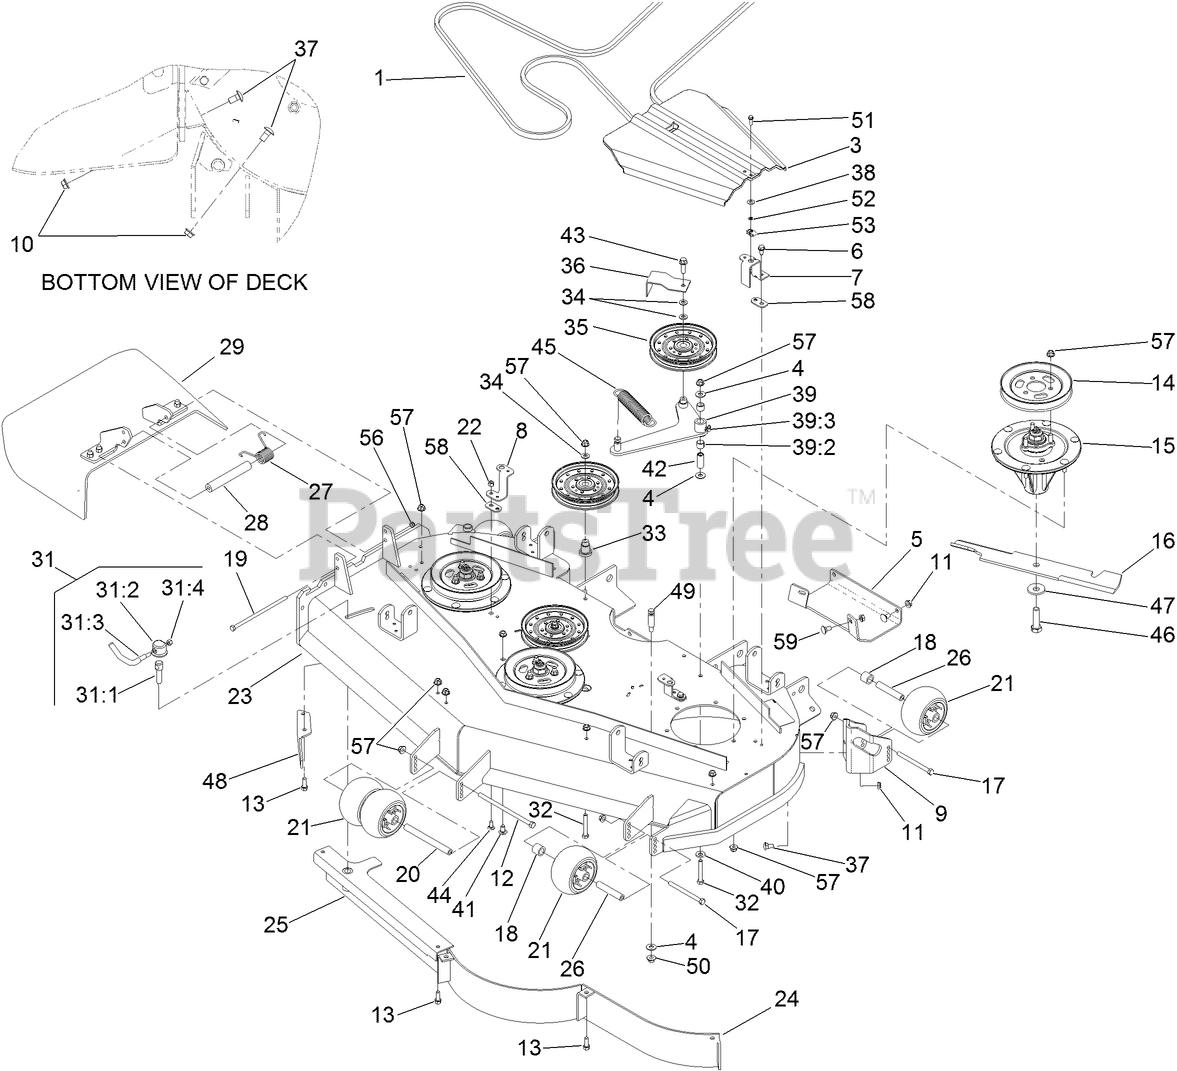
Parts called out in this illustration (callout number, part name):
1	BELT-V
3	COVER-BELT
4	WASHER-FLAT
5	PLATE-SKID
6	SCREW-HWHTF
7	BRACKET-COVER
8	BRACKET-COVER, TALL
9	MOUNT-WHEEL, LH
10	NUT-HHF, WHIZ
12	SCREW-HH
14	PULLEY-B SECTION
15	SPINDLE ASM
16	BLADE-18IN, HI FLOW
17	SCREW-HH
18	TUBE-SPACER
19	SCREW-HH
20	SPACER-WHEEL
21	ROLLER-SCALP, ANTI
22	NUT-LOCK, NI
26	TUBE-SPANNER
27	SPRING-TORSION
28	SPACER
29	RUBBER DEFLECTOR ASM
31	LEVER ASM
31:1	SCREW-LOCK
31:2	CAP-LOCK
31:4	NUT-LOCK, NI
32	SCREW-HH
33	MOUNT-PULLEY
34	WASHER-FLAT
36	GUIDE-BELT
37	SCREW-HH
38	WASHER-THRUST
39	DECK IDLER ARM ASM
39:2	SLEEVE-BEARING
39:3	FITTING-GREASE, 90 DEG
40	WASHER-BELLEVILLE
41	SCREW-CARR
42	BUSHING
43	SCREW-HHF
44	SCREW-CARR
45	SPRING-EXTENSION
46	SCREW-BLADE
47	WASHER-BLADE BOLT, HEAVY
48	BAFFLE-DISCHARGE
49	PIN-THREADED, SPRING ANCHOR
50	NUT-HF
51	SCREW-HWH
52	NUT-RETAINER
56	NUT-LOCK, NI
57	NUT-HF, NI
58	SPACER-BELT COVER
59	SCREW-CARR
